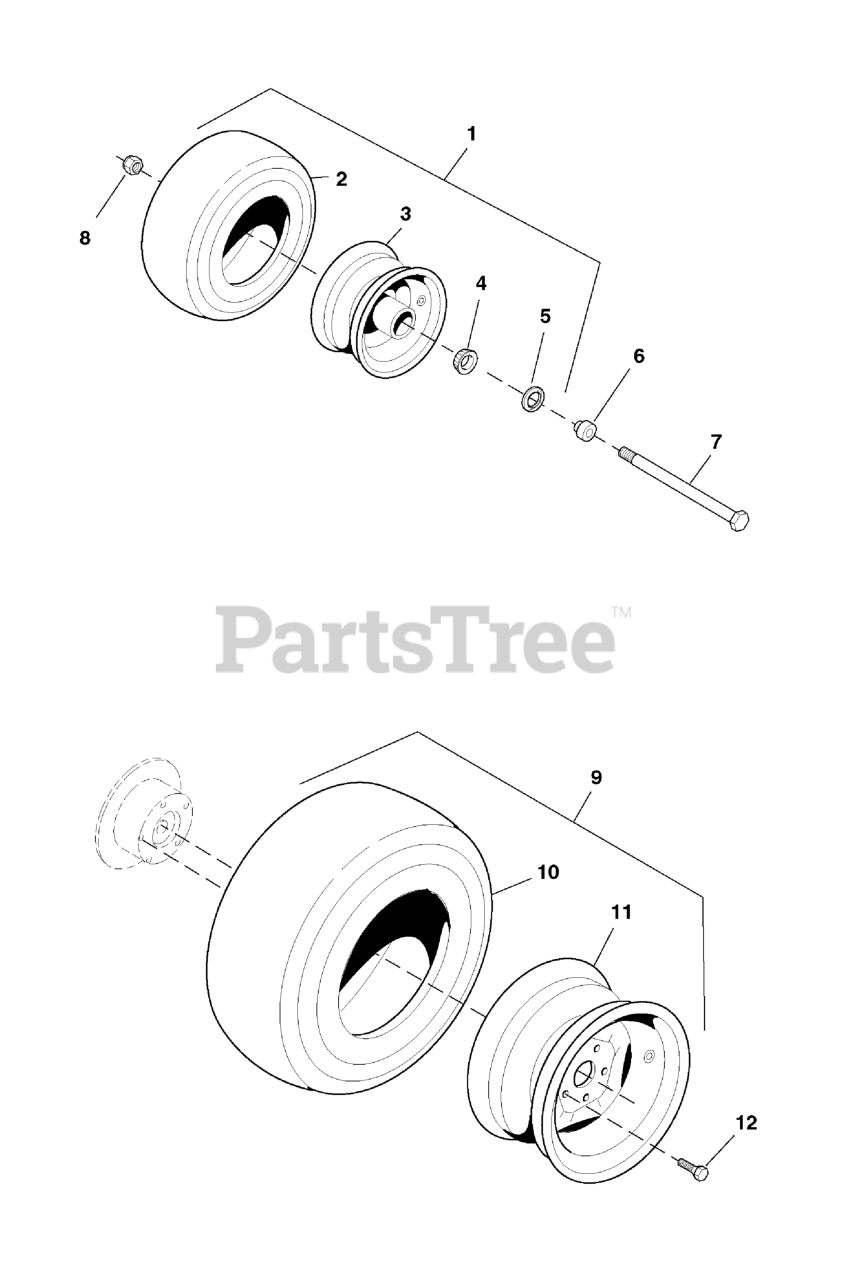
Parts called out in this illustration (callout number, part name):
1	TIRE ASSM, 13 X 6.5 - 6, PNE / TB
2	TIRE, RUBBER ONLY
3	WHEEL ASSEMBLY, for 13 x 6.5 x 6 Tires, Complete
4	BEARING, Tapered Roller
5	SEAL, GREASE
6	ADAPTER, CASTER AXLE, CZ
7	BOLT, 1/2-13 x 8-1/2
8	NUT, 1/2-13 HEX NYLON LOCK
9	WHEEL & TIRE ASSEMBLY, 24 x 12 x 12, Complete
10	TIRE, Rear, 24 x 12 x 12
11	WHEEL ASSEMBLY, for 24 x 12 x 12 Tires
12	WHEEL LUG, 1/2 x 1-5/8
